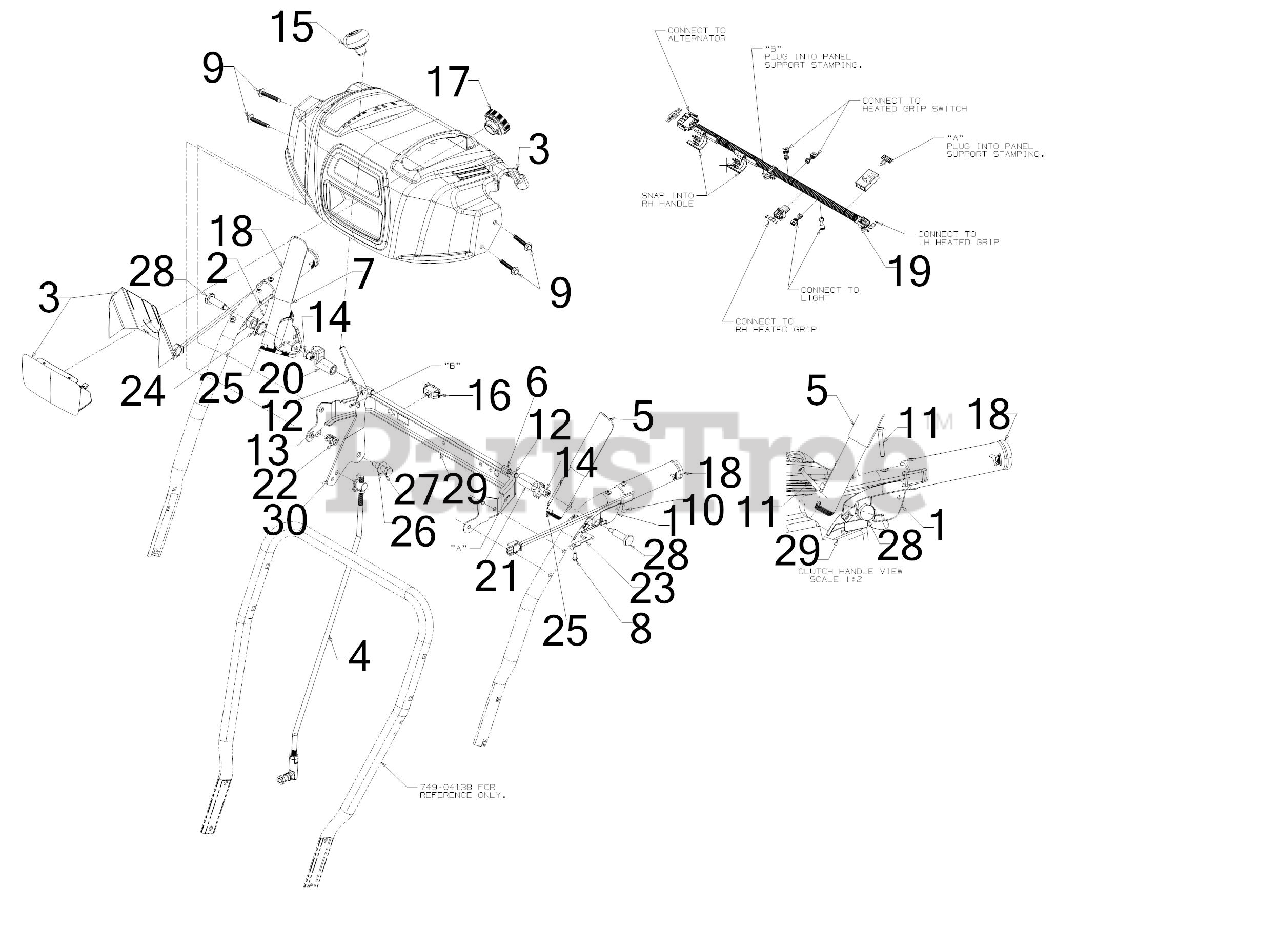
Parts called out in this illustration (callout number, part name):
1	CLUTCH LOCK HANDLE ASSEMBLY (LH)
2	CLUTCH LOCK HANDLE ASSEMBLY (RH)
3	HANDLE PANEL ASSEMBLY
4	SHIFT ROD ASSEMBLY
5	HANDLE ASSEMBLY (LH)
7	ENGAGEMENT HANDLE ASSEMBLY (RH) (BLACK)
8	SCREW #8-16 x .50
9	SCREW 1/4-20 x 1.625
10	SCREW #10-16 x .625
11	SCREW #10-24 x 1.375
12	SCREW 1/4-20 x .50
13	FLANGE LOCK NUT
14	HEX NUT W/PATCH
15	SHIFT KNOB
16	HEATED GRIP SWITCH
17	HEADLIGHT ASSEMBLY
19	HEATED GRIPS HARNESS
21	CLUTCH LOCK CAM
22	COMPRESSION SPRING
23	CLUTCH SPRING
24	TORSION SPRING
25	RUBBER BUMPER
26	FLAT WASHER
27	SHOULDER SCREW
28	SHOULDER SCREW .437 x 1.345 1/4-20
29	HANDLE SUPPORT BRACKET
